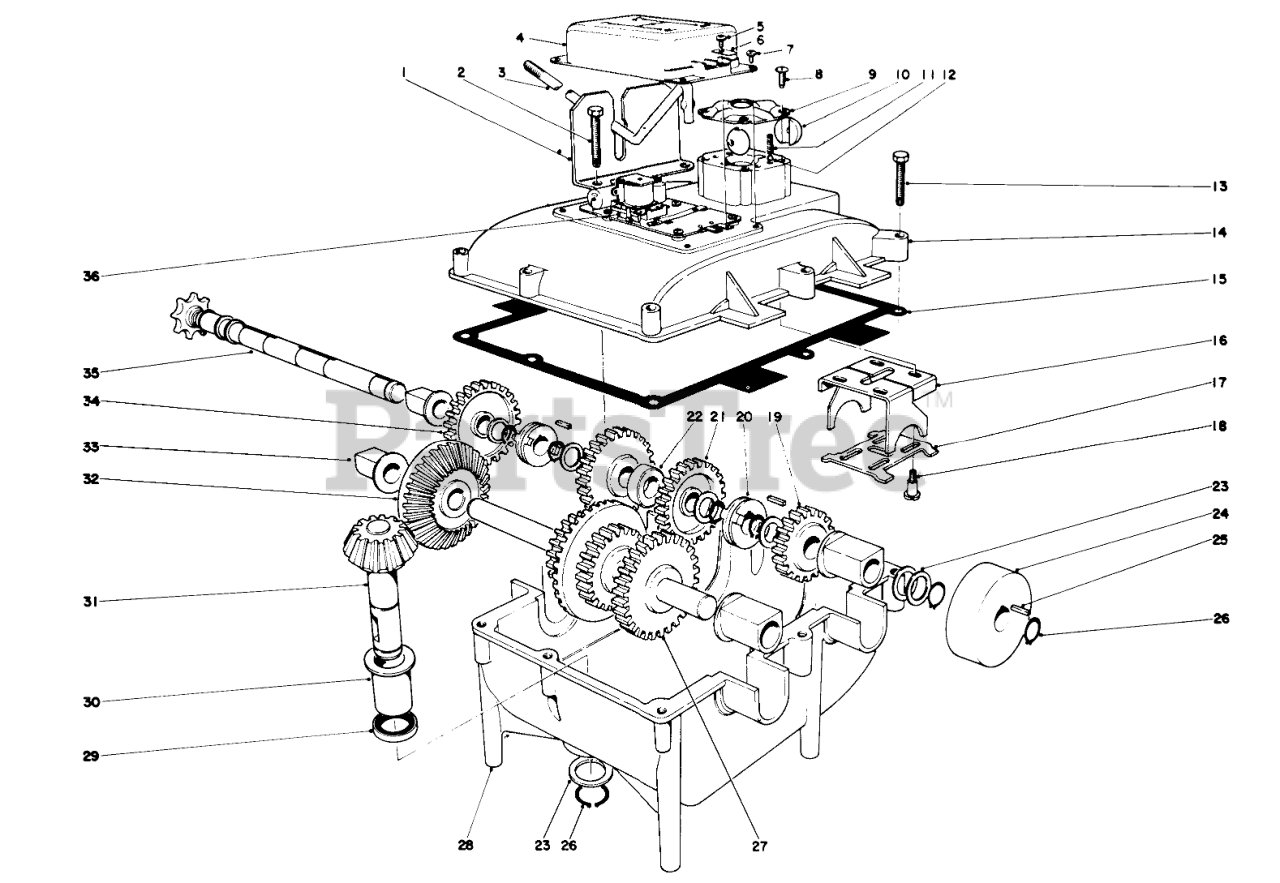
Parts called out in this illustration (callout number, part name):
1	Bracket Shift
3	Shift Rod
4	Housing-Ign. Interlock
6	Terminal
9	Cap Shift
10	Ball Shift Segment
11	Spring
12	Ball-Detent
14	Cover-Gear Housing
15	Gasket
16	Yoke Shift
17	Plate-Backing
18	Screw Shoulder
19	Gear-24 Teeth
20	Dog Driving
21	Gear-30 Teeth
22	Spacer
23	Flat Washer
24	Brake Drum
26	RING-SNAP, EXTERNAL
27	Assembly-Drive Shaft
28	Housing Gear
29	Grease Seal
30	Bushing
31	Assembly-Pinion Shaft
32	Bevel Gear
33	Bearing
34	Gear 36 Tooth
35	Shaft Sprocket
36	Assembly Ign. Interlock
